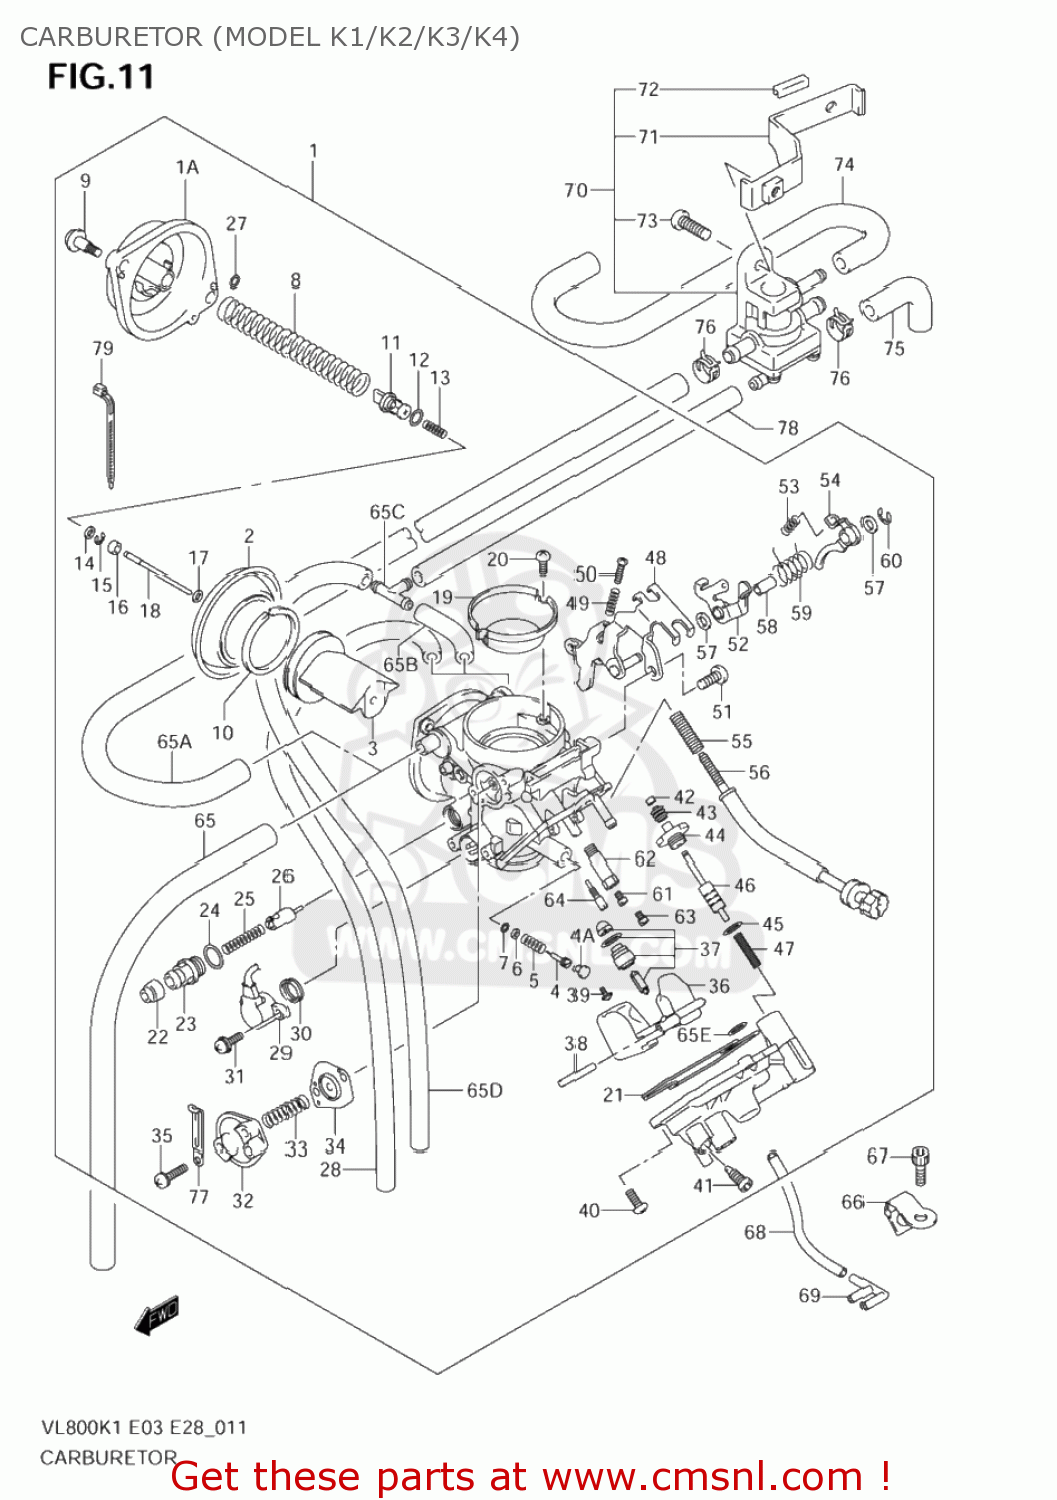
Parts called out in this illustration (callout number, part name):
1	CARBURETOR ASSY
1A	COVER,DIAPHRAGM
2	DIAPHRAGM
3	PISTON VALVE
4	ADJUSTER
4A	PLUG
5	SPRING,THROTTLE SCREW
6	WASHER
7	O RING,PILOT AIR SCREW
8	SPRING
9	SCREW
10	RING
11	HOLDER
12	O RING(D:1.9,ID:4.8)
13	SPRING
14	WASHER
15	E RING,MULTIPLE JET NOZZLE
16	RING
17	WASHER
18	JET,NEEDLE(5E23-1)
19	FUNNEL
20	SCREW
21	O RING
22	CAP
23	HOLDER,GUIDE
24	O RING
25	SPRING
26	PLUNGER ASSY
27	O RING
28	HOSE
29	SENSOR ASSY
30	GASKET,THROTTLE SHAFT (NAS)
31	SCREW
32	COVER ASSY
33	SPRING
34	DIAPHRAGM ASSY
35	SCREW
36	FLOAT ASSY
37	VALVE ASSY,NEEDLE
38	PIN,FLOAT
39	SCREW
40	SCREW
41	SCREW,DRAIN
42	CAP
43	CAP
44	GUIDE HOLDER
45	O RING(D:1.5,ID:8.5)
46	PLUNGER
47	SPRING
48	BRACKET ASSY
49	SPRING,STARTER SHAFT
50	SCREW
51	SCREW
52	LEVER ASSY
53	SPRING,THROTTLE SCREW
54	LEVER ASSY
55	SPRING
56	SCREW,ADJUST
57	WASHER
58	RING
59	SPRING
60	E RING,ACCELETION LEVER
61	JET,MAIN (132.5)
62	HOLDER,JET
63	JET,MAIN(55)
64	JET,PILOT(27.5)
65	HOSE(7X10X250)
65A	HOSE (7X11X1000)
65B	HOSE(4X8X50)
65C	NIPPLE
65D	HOSE(4X8X400)
65E	O RING
66	PLATE,IDLE ADJUST
67	BOLT,VAC.PIPE
68	HOSE(4X8X600)
69	JOINT
70	VALVE,AIR VENT
71	BRACKET
72	PROTECTOR
73	SCREW, 6X20
74	HOSE,AIR VENT VALVE
75	HOSE, AIR VENT
76	CLIP
77	CLAMP(L:80)
78	HOSE(4X8X600)
79	CLAMP(L:165)
